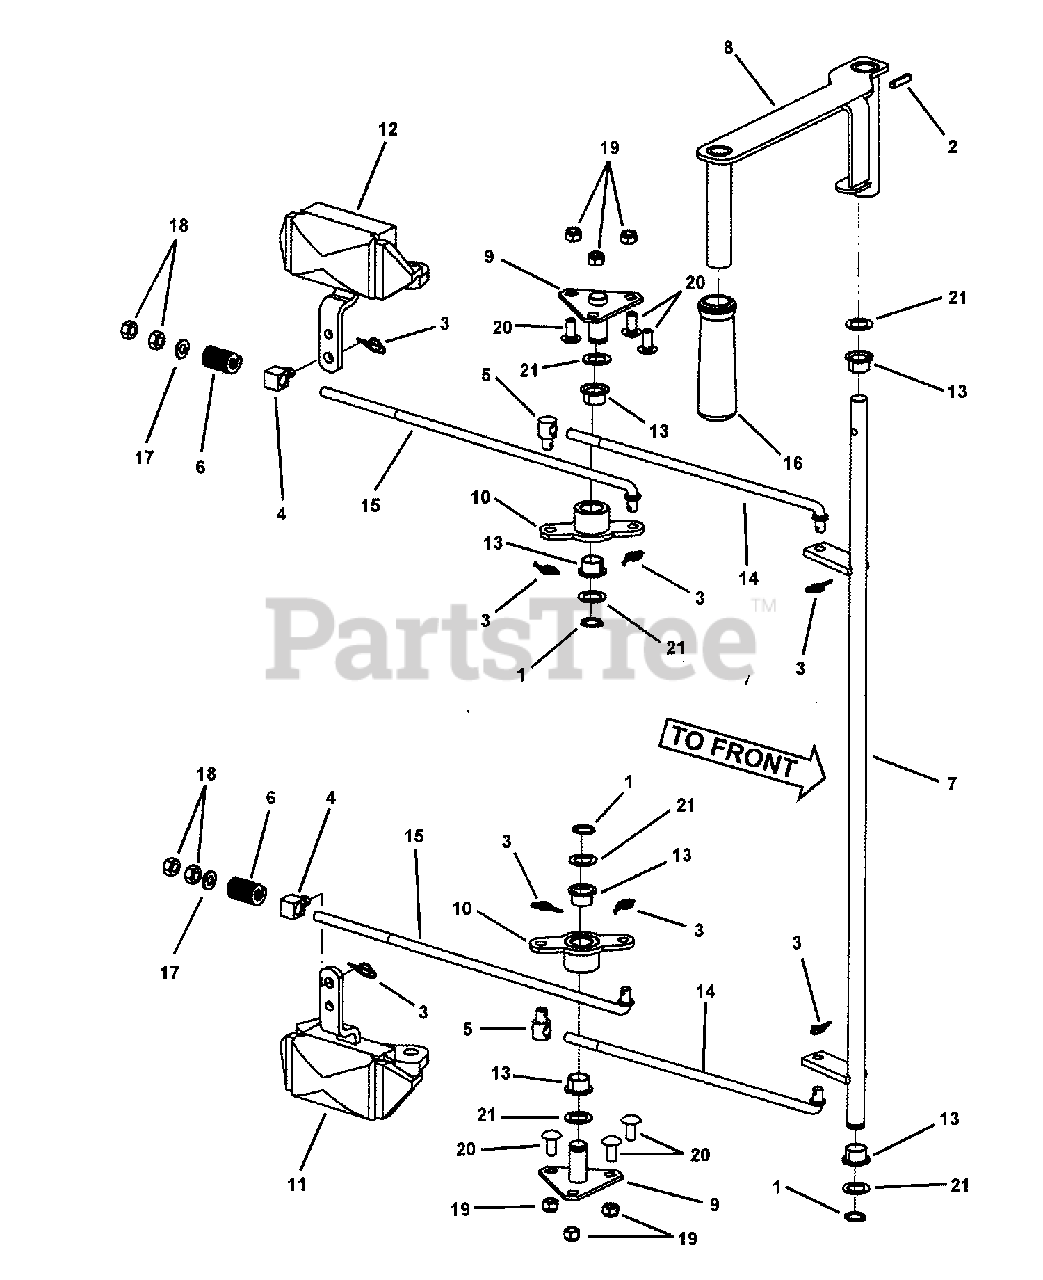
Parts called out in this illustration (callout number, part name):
1	RING, 5/8" External Retaining
2	GROOVE PIN, 1/4 x 1-1/4"
3	PIN, 3/8" Self Locking Cotter
4	SWIVEL, Brake Link-PM
5	SWIVEL, Adjustable
6	SPRING, Rectangular Wire Die, Blue
7	WELDMENT, Brake Rod Crossrod
8	WELDMENT, Park Brake Handle
9	WELDMENT, Brake Linkage Pivot
10	WELDMENT, Brake Linkage Bellcrank
11	PACKAGE, Left Hand Disc Brake
12	PACKAGE, Right Hand Disc Brake
13	BUSHING, Teflon Impregnated
14	LINKAGE, Park Brake, Front (3/8-24 thread)
15	LINKAGE, Park Brake, Rear (3/8-24 thread)
16	GRIP, Parking Brake
17	WASHER, 3/8" Flat
18	NUT, 3/8-24 Hex Jam
19	NUT, 5/16-18 HEX NYLON LOCK
20	BOLT, 5/16-18 x 3/4" Short Neck Carriage GR5
21	WASHER, .64 I.D. Flat
